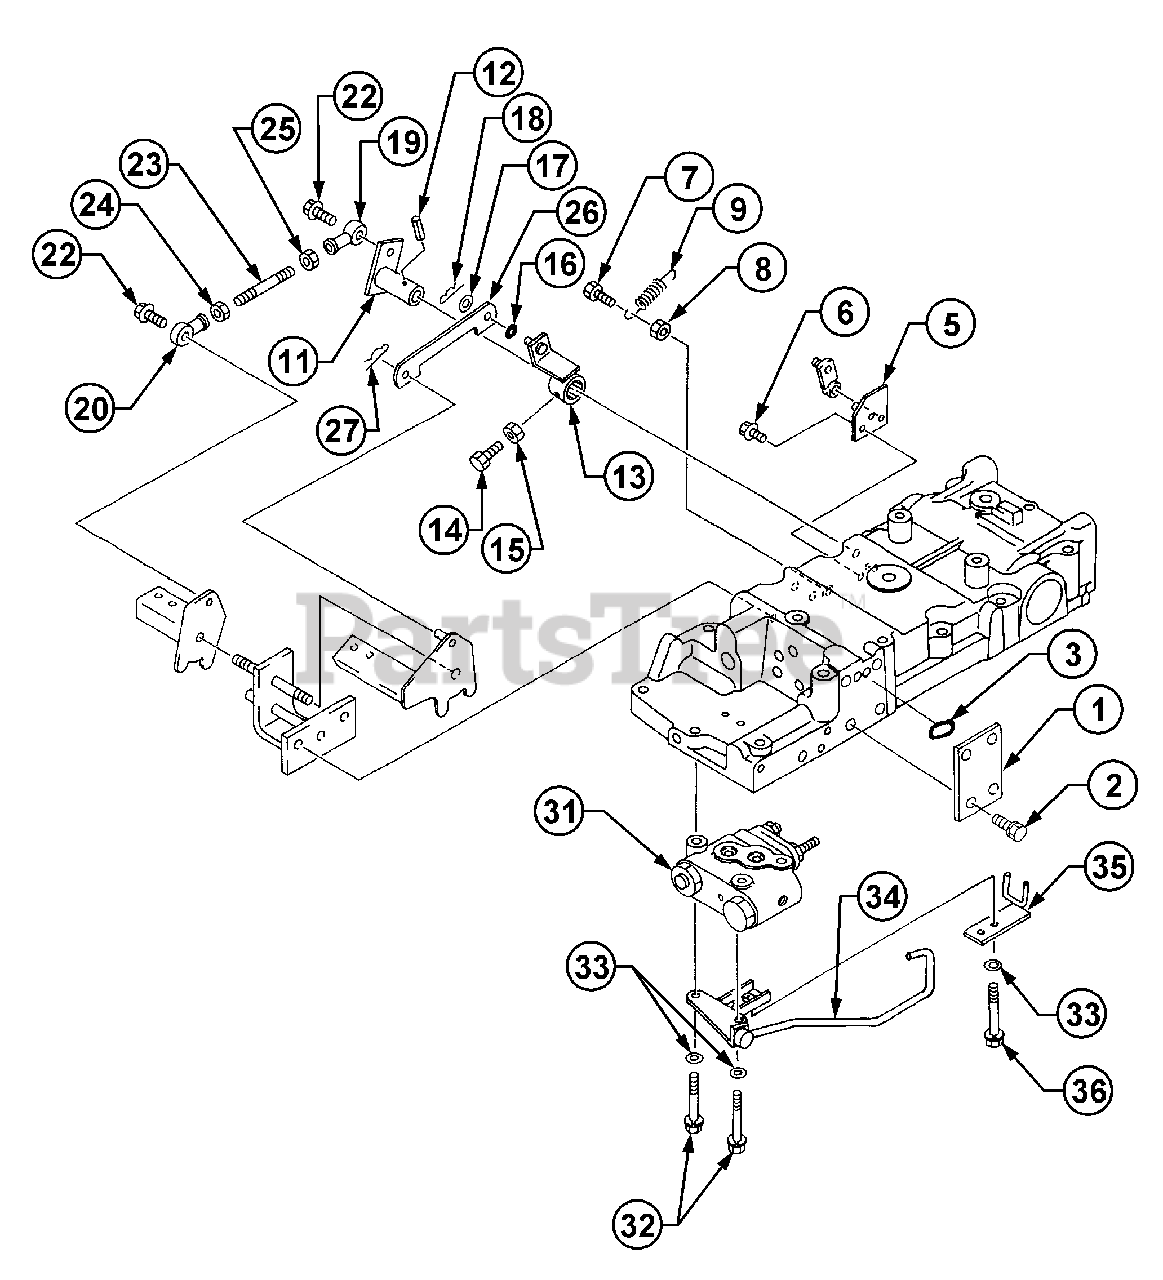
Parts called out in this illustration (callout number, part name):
2	Bolt, w/Washer
19	Link R.H., Ball
20	Link L.H., Ball
22	Bolt, w/Washer
31	Valve, Control
32	Bolt, w/Washer
34	Pipe, Lubricate
